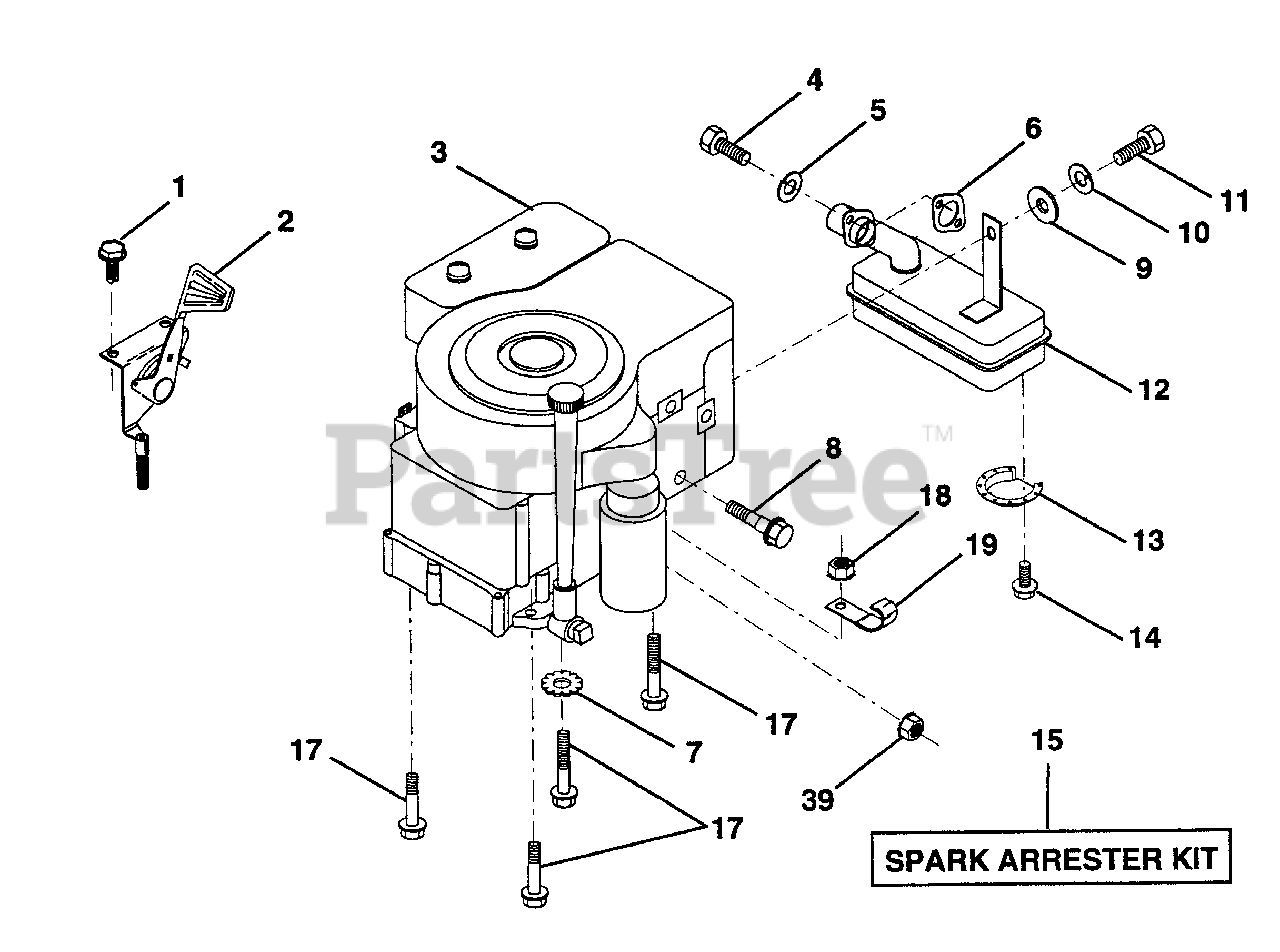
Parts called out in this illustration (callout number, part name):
1	Screw, Hex Head, Thread Cutting 1/4-20 x 1/2
2	Control, Throttle
3	Engine
4	Screw, Hex Cap Hd. 5/16-18 x 3/4
5	Washer, Lock, Heavy Helical Spring 5/16
6	Gasket, Exhaust
7	Washer, Lock Ext. Tooth 3/8
8	Bolt, Shoulder 5/16
9	Washer 5/16 x 3/4 x 16 Gauge
10	Washer, Lock, Heavy Helical Spring 1/4
11	Bolt, Hex, Fin.
13	Deflector, Muffler
14	Screw, Spider lock Hex Hd 8 x 1/2
15	Arrester, Spark
17	Screw, Hex Washer Head, Thd., Roll. 3/8-16 x 1-1/2
18	Nut, Hex, Keps 3/8-16
19	Clip, Fuel Line
39	Nut, Flange 1/4-20
